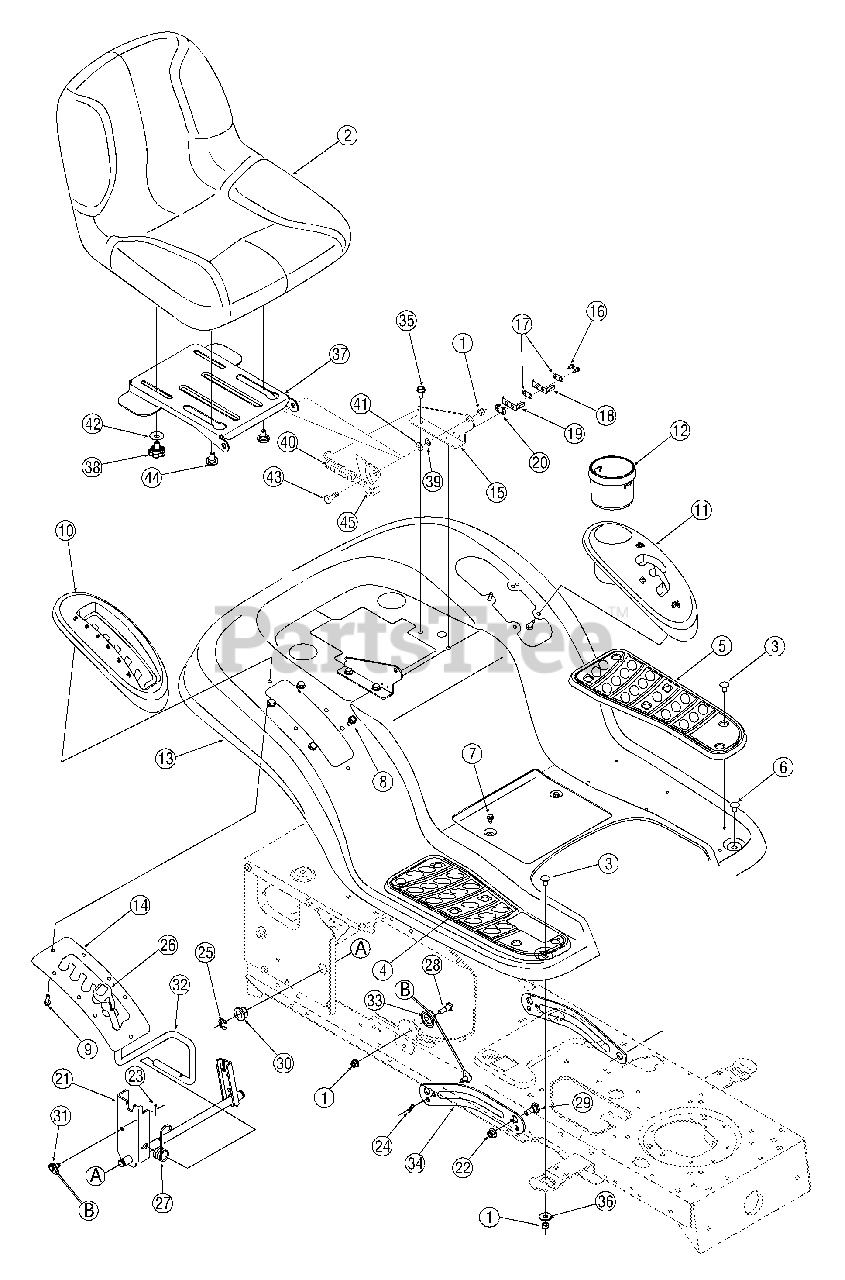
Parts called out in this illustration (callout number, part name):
1	Nut, Flange Lock, 5/16-18, GrF, Nylon
2	Medium Back Seat, Super Bronco
2	Low Back Seat, Bronco
3	Ratchet Clip
4	RH Foot Pad, Rubber, Super Bronco
4	RH Foot Pad, Bronco
5	LH Foot Pad, Rubber, Super Bronco
5	LH Foot Pad, Bronco
6	Bolt, Carriage, 5/16-18,.62, Gr1
7	Screw, 1/4-20, 0.500
8	Screw, 5/16-12, 0.750, Super Bronco
8	Screw, 5/16-18 x.750, Bronco
9	Screw, 1/4-15, 0.750, Super Bronco Only
10	Cover, Lift Lever, Super Bronco Only
11	Cover, w/ Cup Holder, Super Bronco Only
12	Cup Holder, Bronco Only
16	Screw, #8-18 x.50
17	Plate, Insulator
18	Spring Switch, Outer
19	Spring Switch, Inner
20	Plate, Insulator Boss
21	Shaft Assembly, Lift
22	Nut, Flange Lock, 3/8-16, Gr F, Nylon
23	Pin, Cotter,.072 Dia. X. 1.13
24	Pin, Cotter, 3/32, 1.0
25	Ring, E Type,.625 Dia.
26	Grip, Handle, 1/2
27	Spring, Torsion
28	Screw, 5/16-18 x.620 Gr2
29	Screw, Shoulder,.625 x.165, 3/8-16
30	Bearing, Hex Flange
31	Cable, Lift, 16.16
32	Handle, Lift
33	Pulley, Roller
35	Screw, 5/16-12, 0.750
36	Washer, Flat,.344 x 1.0 x.063
38	Knob, 3/8-16
39	Nut, Speed,.3125 ID
40	Spring, Extension,.84 Dia. x 4.6
41	Washer, Flat,.344 x.688 x.065
42	Washer, Flat,.406 x 1.00 x.030
43	Screw, Shoulder,.437 x.268, 5/16-18
44	Shoulder Screw
45	Seat Bracket, Lift
